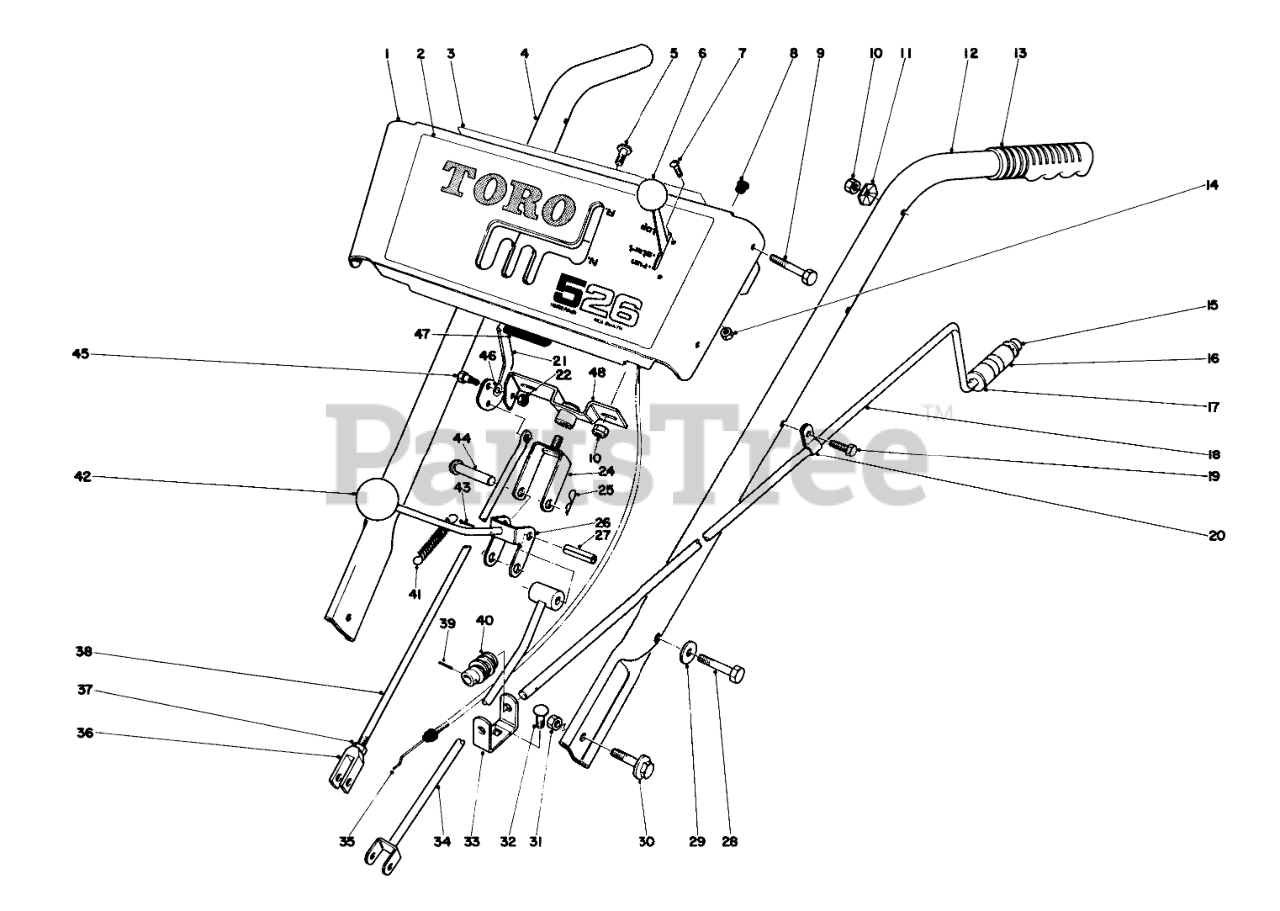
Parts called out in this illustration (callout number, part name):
1	Escutcheon Plate (Incl. Ref. 2 & 3)
2	Decal
3	Decal
4	Handle, R.H.
5	Screw, Machine
6	KNOB-CONTROL
7	SCREW-PPH
9	SCREW-HH
10	NUT-LOCK
11	Washer
12	Handle, Left
13	Grip Handle
14	Nut
15	Speed Nut
16	Chute Control Grip
17	WASHER-FLAT
18	ROD CHUTE CONTROL
19	Hex Hd. Screw
20	R-CLAMP
21	Handle, Auger
22	NUT-LOCK
24	Pivot Bracket
25	PIN-HAIR
26	Rod Shift
27	PIN-ROLL
28	SCREW-HH
29	WASHER-FLAT
30	SCREW-HHF
31	NUT-HEX
32	SCREW-CARR
33	WORM BRACKET
34	Trunnion
35	Control-Throttle
36	Yoke
37	NUT-HJ
38	Drag Link
39	PIN-SPRING
40	GEAR-WORM, CHUTE
41	CONT ROD SPRING 0
43	PIN-COTTER
44	PIN-CLEVIS
45	SCREW-SHOULDER
46	WASHER-PLAIN
47	AUGER CLUTCH HND GRIP
48	SWIVEL BLOCK WA
